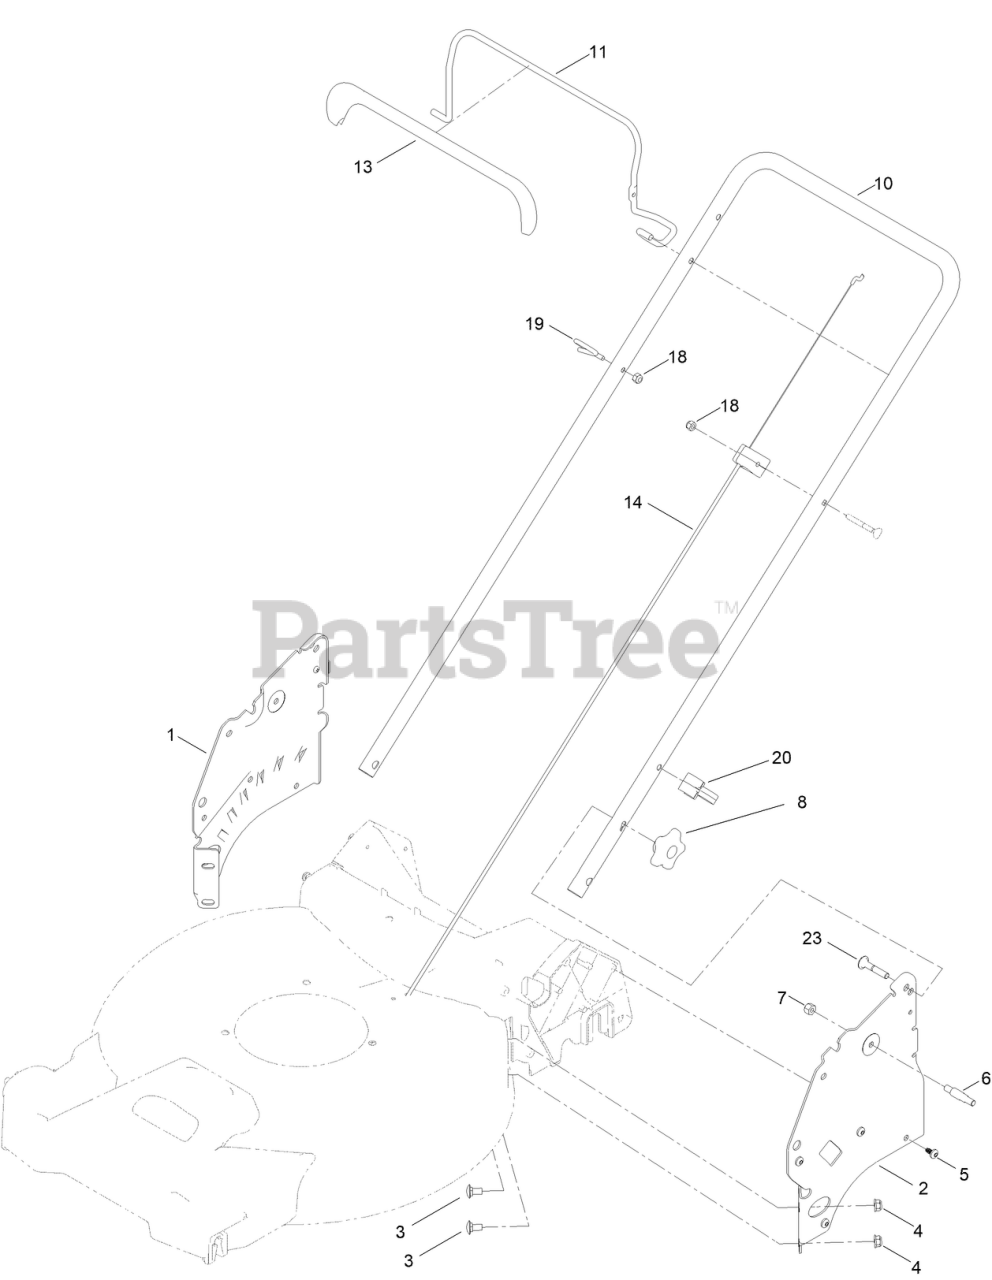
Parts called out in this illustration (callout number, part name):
1	PLATE-HOC, RH
2	PLATE-HOC, LH [BLK-TXT]
3	SCREW-CARR
4	NUT-FLANGE, NI
5	SCREW-PLASTIC,PH
6	BOLT-SHOULDER, HANDLE
7	NUT-LOCK, NI
8	KNOB-HANDLE
10	HANDLE-UPPER
11	BAIL-BRAKE
13	COVER-BAIL
14	CABLE-BRAKE, ENGINE
18	NUT-LOCK, NI
19	GUIDE-ROPE
20	GUIDE-CABLE
23	SCREW-CARR
